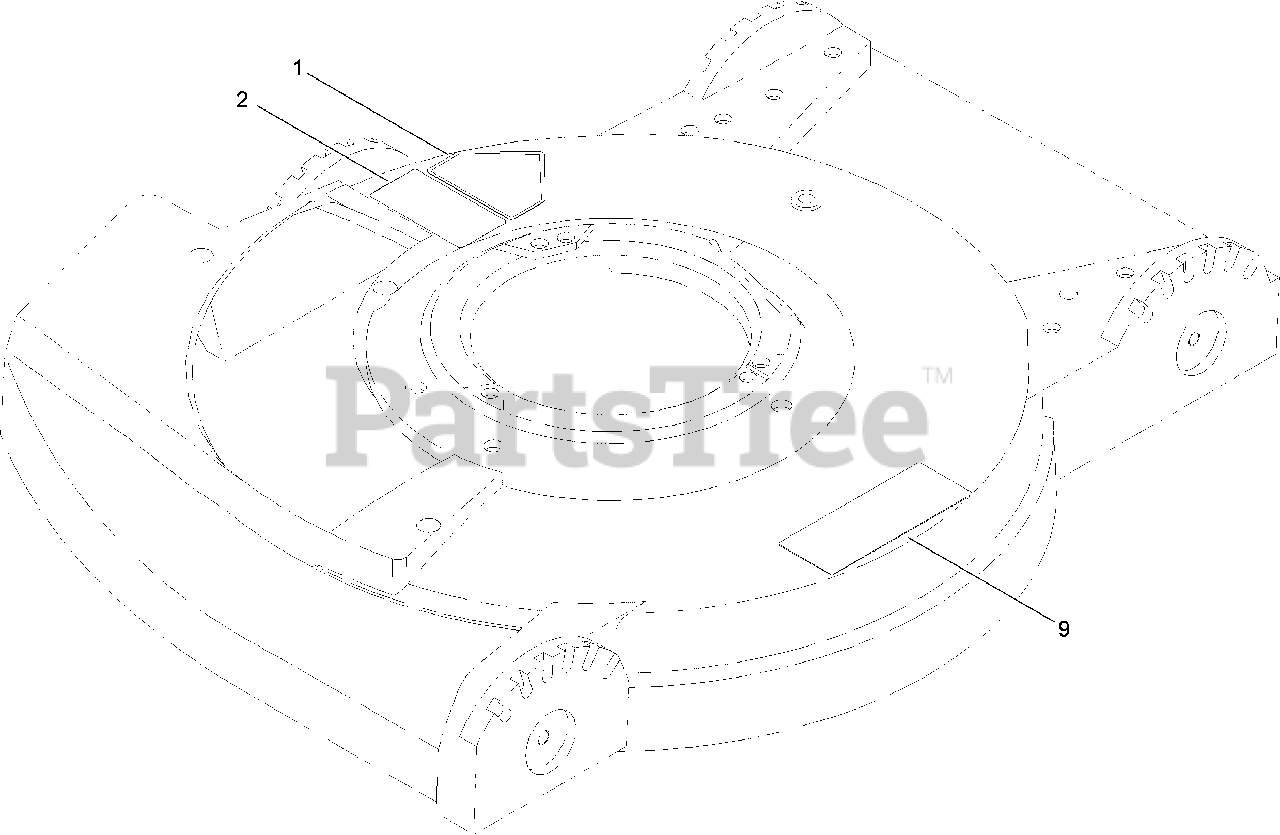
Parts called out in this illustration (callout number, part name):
1	DECAL-DANGER
2	DECAL-DANGER
9	DECAL-WARNING
